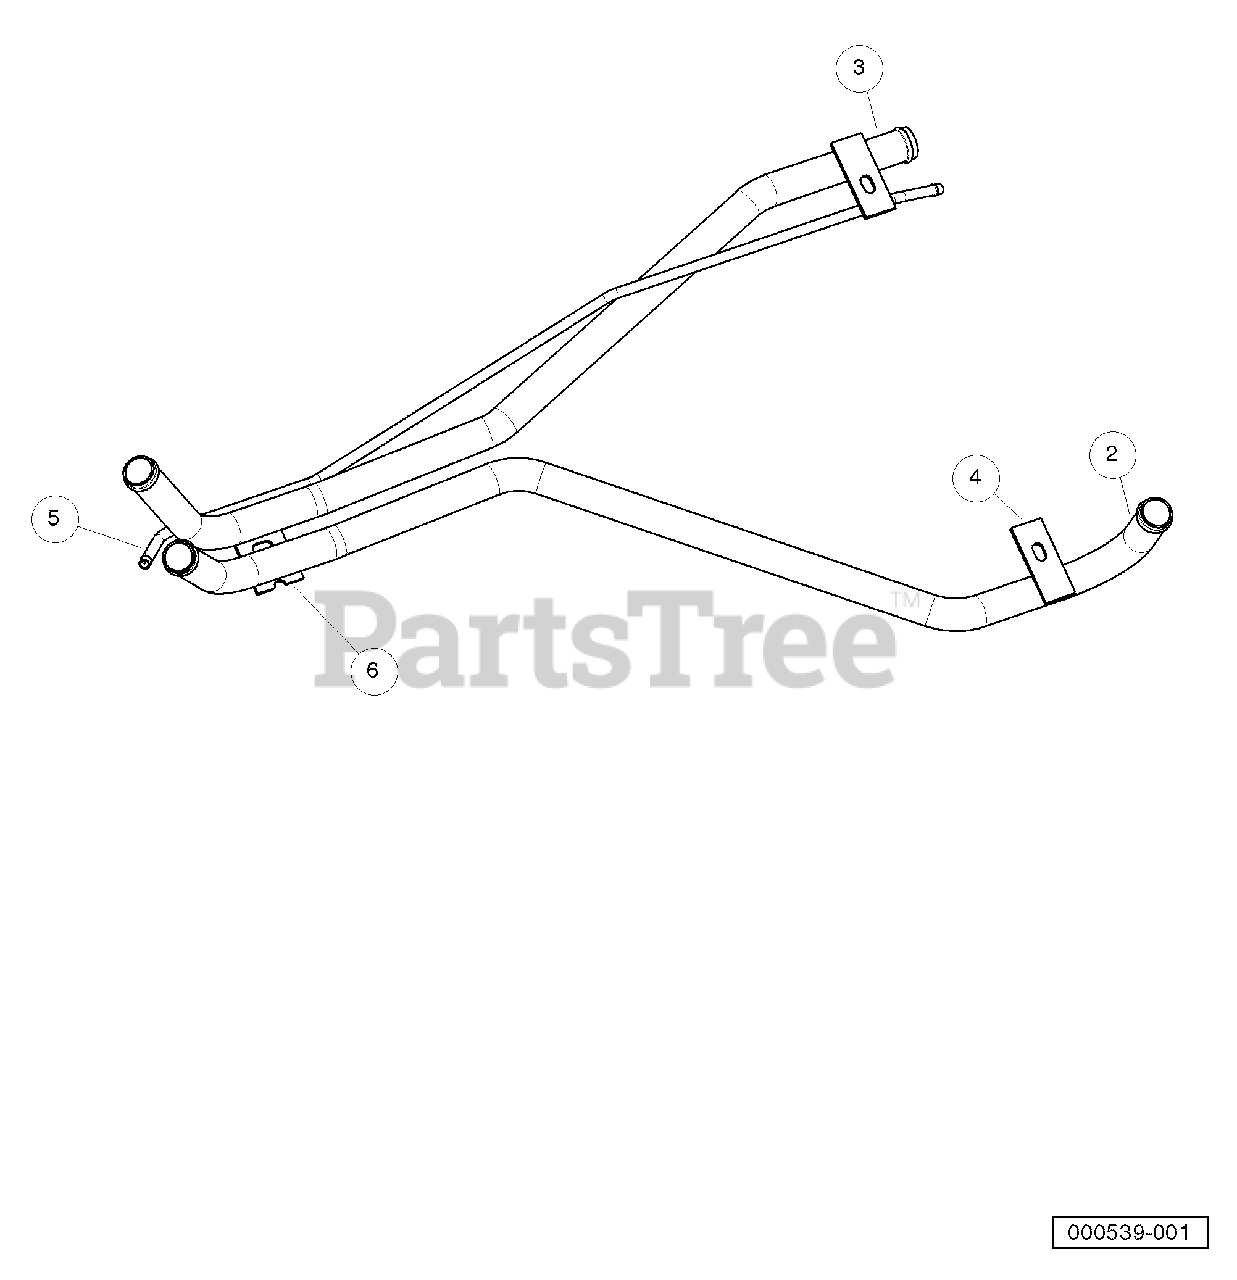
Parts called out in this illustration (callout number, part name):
1	Weldment, Group, Coolant Pipe
2	Pipe, Coolant Upper
3	Pipe, Coolant Lower
4	Tab, Rear Mntg, Coolant Pipe
5	Pipe, Vent, Coolant
6	Tab, Cooling Pipe Mount
